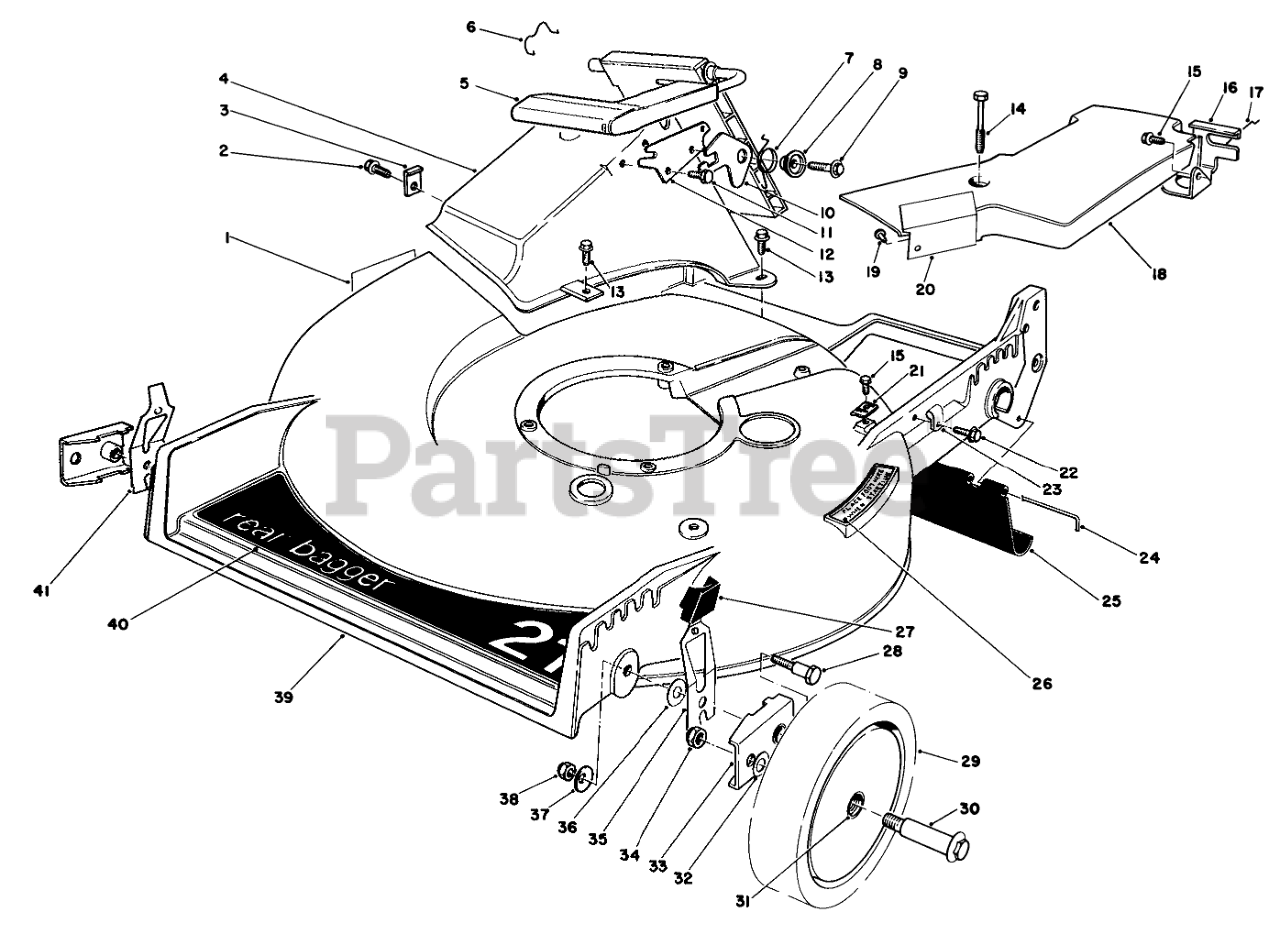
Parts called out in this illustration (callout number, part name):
1	DECAL-DANGER
2	SCREW
3	TUNNEL CLIP
4	Tunnel Discharge
5	Discharge Door Assembly
6	DOOR RET SPRING
7	TORSION SPRING
8	DOOR SPACER
9	SCREW-HWH
10	SAFETY LATCH
11	SCREW-PLASTITE
12	DOOR LATCH PLATE
13	SCREW-HWH
14	SCREW-HHFTF
15	SCREW-HWHTF
16	Bracket-Traction Adj.
17	RETAINER-CABLE
18	Belt Cover Assembly (Incl. Ref. #19 & 20)
19	RIVET-HEAD, FLAT
20	HEAT SHIELD
21	Cable Clamp
22	SCREW
23	CLAMP-CABLE
24	ROD-SHIELD
25	SHIELD-TRAILING
26	STEP PAD DECAL
27	KNOB-ARM
28	PIVOT SCREW
29	Wheel & Tire Assembly (Incl. Ref. #31)
30	WHEEL BOLT
31	BUSHING
32	WASHER
33	HP PIVOT ARM ASM
34	NUT-LOCK
35	L. HP SPRING ARM ASM
36	WASHER-PIVOT
37	WASHER-BELLEVILLE
38	NUT-LOCK, NI
39	Housing (Incl. Ref. #1, 13 & 26)
40	DECK DECAL
41	R HP SPRING ARM ASM
